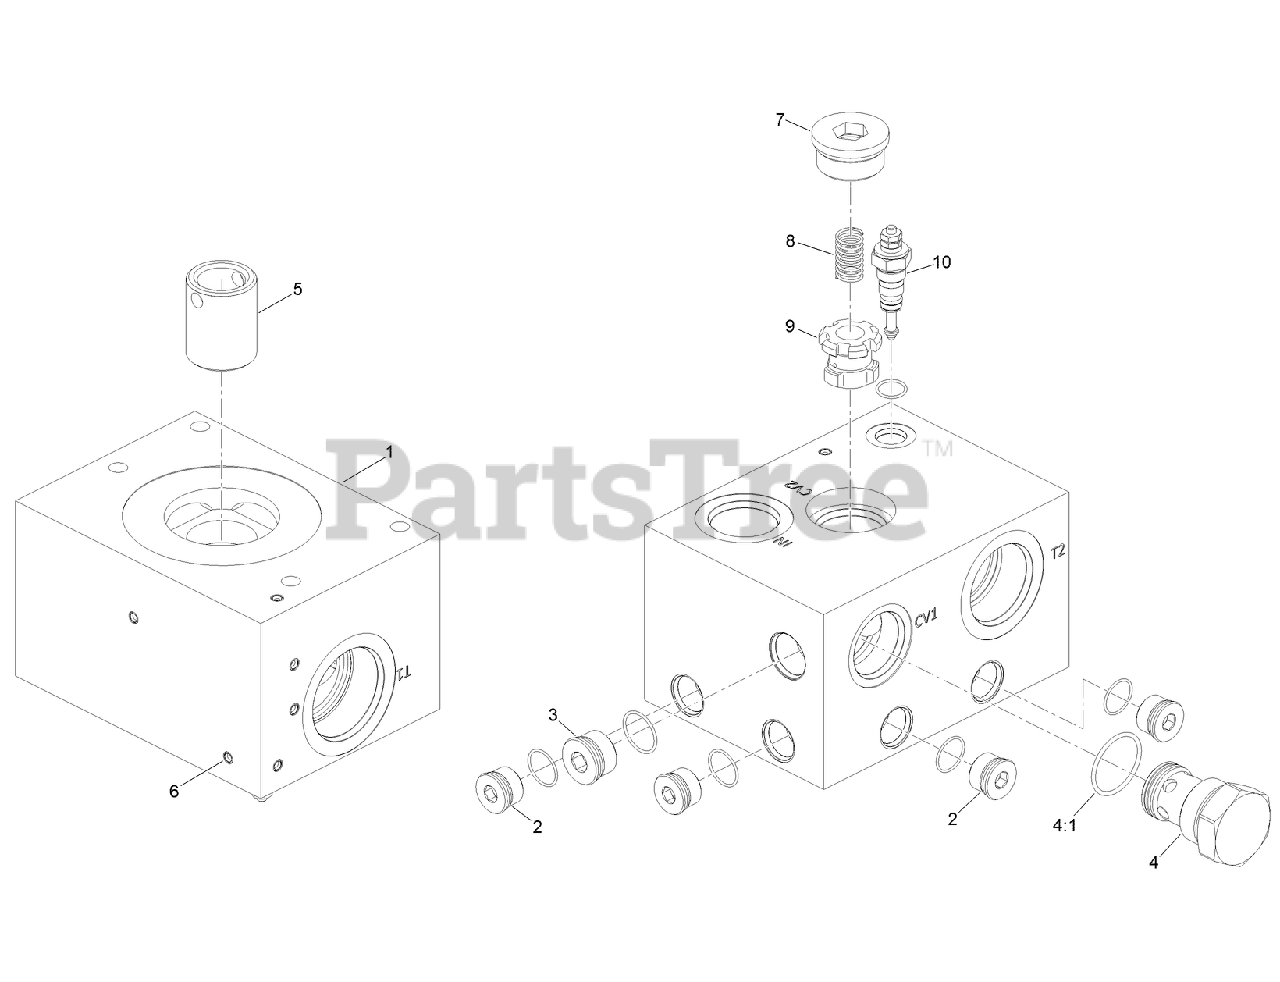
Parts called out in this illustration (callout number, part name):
1	BLOCK-MANIFOLD
2	PLUG-HYD
3	PLUG-LEAK, ZERO
4	VALVE-CHECK
4:1	SEAL KIT
5	NIPPLE-FILTER
6	Deck ASM
7	PLUG-SOCKET, HEX
8	SPRING-COMPRESSION
9	VALVE-POPPET
10	SWITCH-INDICATOR, ELEC
